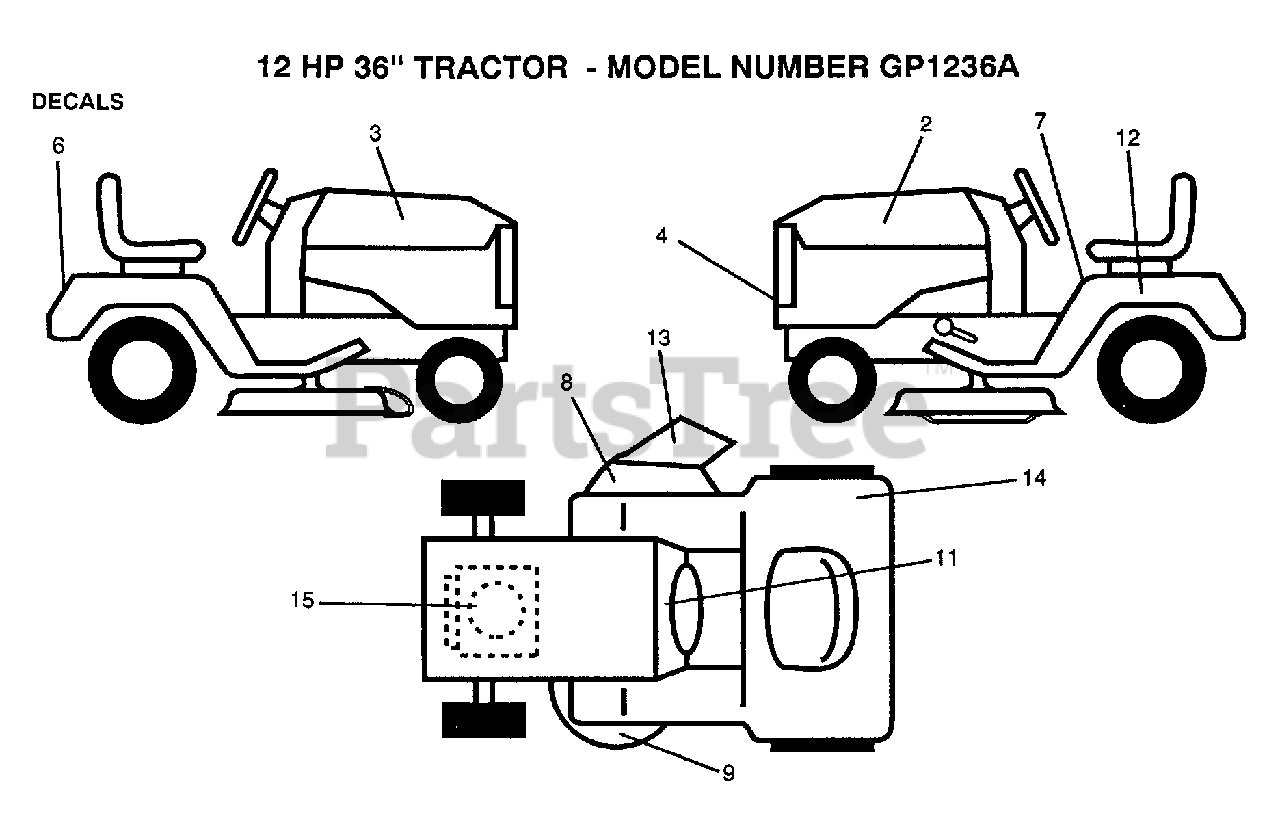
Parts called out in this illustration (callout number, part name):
3	DECAL, STRIPE, HOOD, R.H.
6	DECAL, FENDER
7	DECAL CAUTION
8	DECAL WARNING
9	DECAL YT
12	DECAL
13	DECAL WARNING
15	DECAL.ENG.271967
